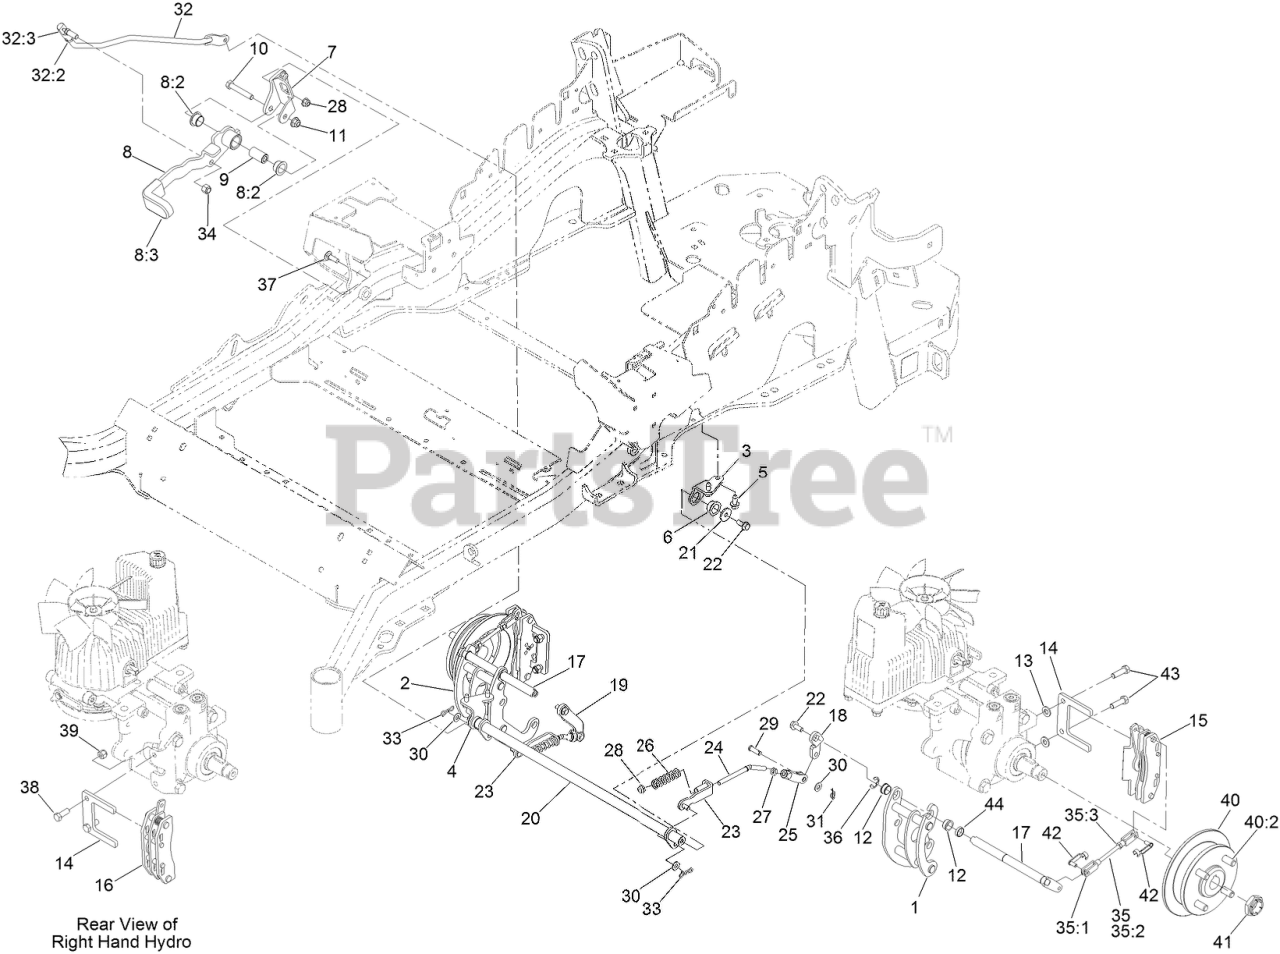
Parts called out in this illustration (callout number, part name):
1	MOUNT-BELLCRANK, LH
2	MOUNT-BELLCRANK, RH
3	MOUNT-PIVOT, LH
4	MOUNT-PIVOT, RH
5	Screw-HWH 5/16-18 X 3/4 Tf
6	BUSHING-FLANGE
7	BRACKET-MOUNT
8	BRAKE LEVER ASM W/ GRIP
8:2	BUSHING-FLANGE
8:3	GRIP-LEVER
9	HANDLE-PIVOT, BRAKE
10	SCREW-HH
11	NUT-HF, NI
12	BUSHING
13	WASHER-FLAT
14	PLATE-MOUNT, BRAKE
15	CALIPER-BRAKE
16	CALIPER-BRAKE, RH
17	BELLCRANK
18	ARM-INNER, LH
19	ARM-INNER, RH
20	SHAFT-CROSS
21	WASHER-FLAT
22	SCREW-HHF
23	BRACKET-L
24	LINKAGE-MID
25	YOKE-OFFSET
26	SPRING-COMPRESSION
27	NUT-JAM
28	NUT-HF, NI
29	PIN-CLEVIS
30	WASHER-PLAIN
31	PIN-COTTER, LOCKING
32	FRONT LINKAGE ASM
32:2	END-TIE ROD, RH
32:3	NUT-HJ
33	PIN-COTTER, LOCKING
34	NUT-LOCK
35	REAR LINKAGE ASM
35:3	NUT-JAM
37	BOLT-CARR
38	SCREW-HH
39	NUT-LOCK, NI
40	WHEEL HUB ASM
40:2	STUD-WHEEL
41	LOCKNUT
42	PIN-CLEVIS, SPRING
43	SCREW-LOCK, PATCH
